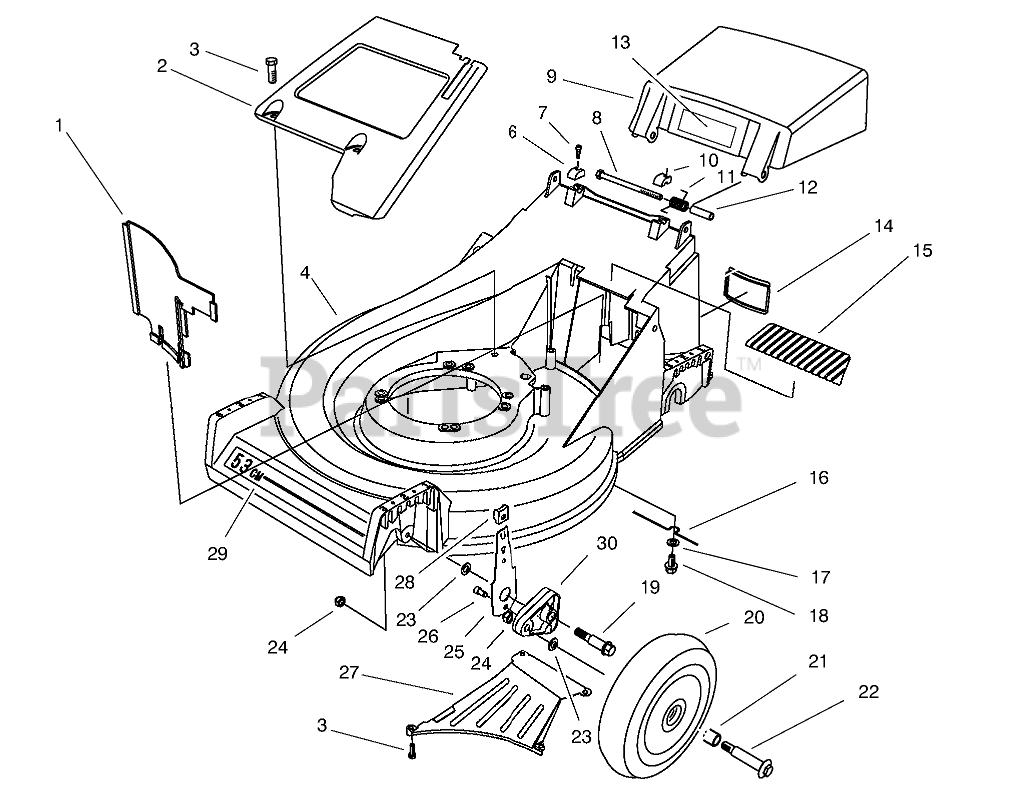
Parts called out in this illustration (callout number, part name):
1	PANEL-VERTICAL
2	PaneI-Screen
3	SCREW-HWHTF
4	Housing-53cm (Incl. Ref. #5 & 29)
6	CAP-HINGE BOLT, RH
7	SCREW-HSH
8	SCREW-HH
9	Door-Discharge (Incl. Ref. #13)
10	CAP-HINGE BOLT, LH
11	SPRING-DOOR
12	SPACER-DOOR
13	DECAL-DANGER
14	COVER-ACCESS
15	COVER-TOP
16	RETAINER-BELT
17	WASHER-FLAT
18	SCREW-HHFTF
19	BOLT-SHOULDER
20	Wheel & Tire Assembly (Incl. Ref. #21)
21	BUSHING
22	WHEEL BOLT
23	WASHER
24	NUT-LOCK
25	FRONT SPRING ARM ASM
26	SCREW-HSH, THREAD FORMING
27	Ramp-Discharge
28	KNOB-ARM
29	DECAL
30	ARM-PIVOT, FRONT
